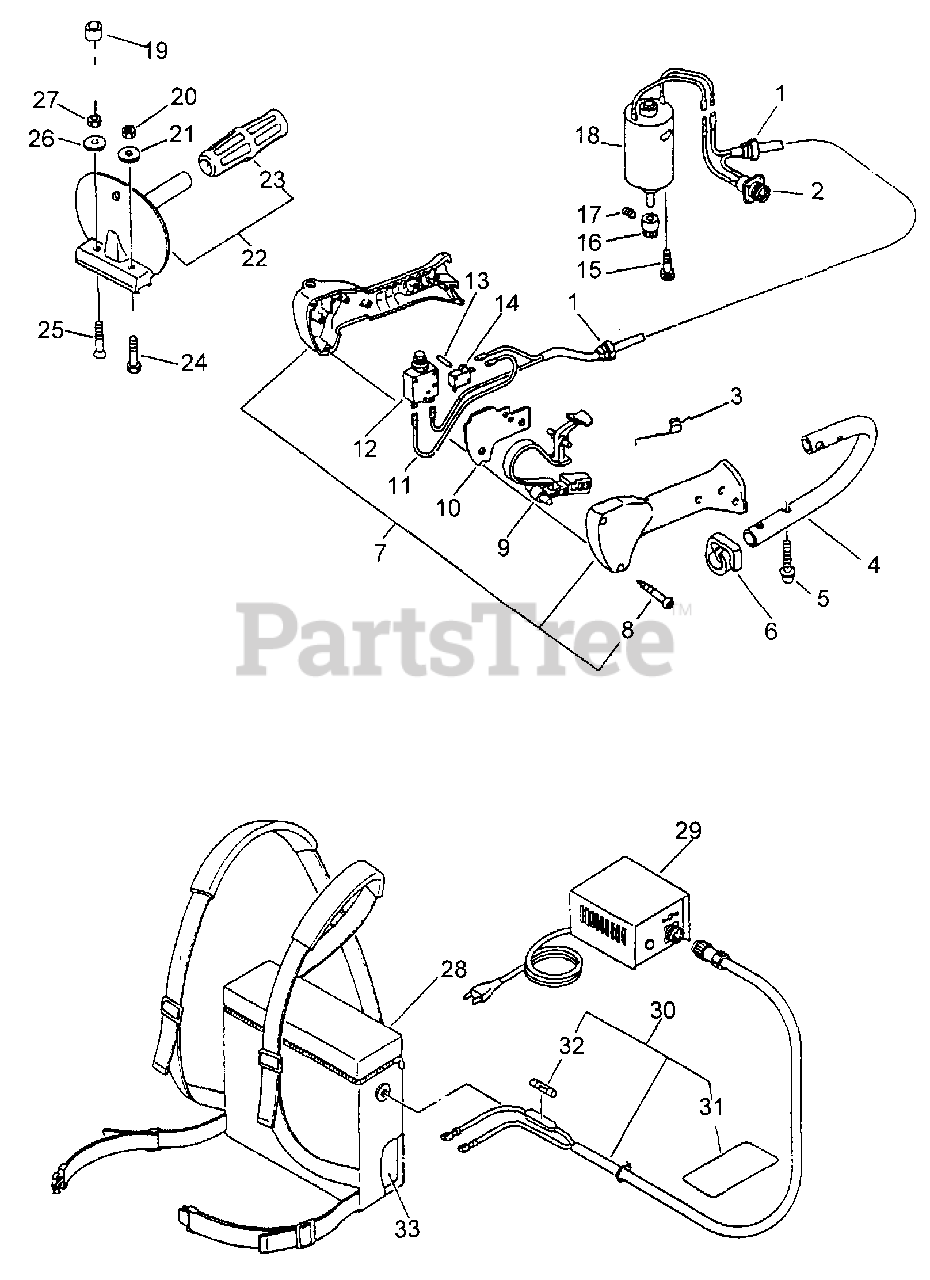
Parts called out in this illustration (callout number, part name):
1	GROMMET, CABLE
2	HARNESS, WIRE
3	SPRING
4	HANDLE - REAR
5	SCREW 5×25
7	GRIP, HANDLE
8	SCREW 4×22
9	TRIGGER, THROTTLE
10	PLATE, PARTITION
11	LEAD - GROUND
12	PROTECTOR, CIRCUIT
13	PIN, STRAIGHT
14	IGNITION SWITCH ASSY
15	BOLT 5×30
16	GEAR, SPUR
17	SCREW SET 4×5
18	MOTOR ASSY
19	INSERT
20	NUT, LOCK 6
22	HANDLE ASSY
23	GRIP, HANDLE
24	BOLT 6×35
25	SCREW 5×30
26	WASHER
27	NUT, LOCK M5
28	CASE, BATTERY
30	HARNESS, WIRE
31	LABEL - CAUTION
32	FUSE
